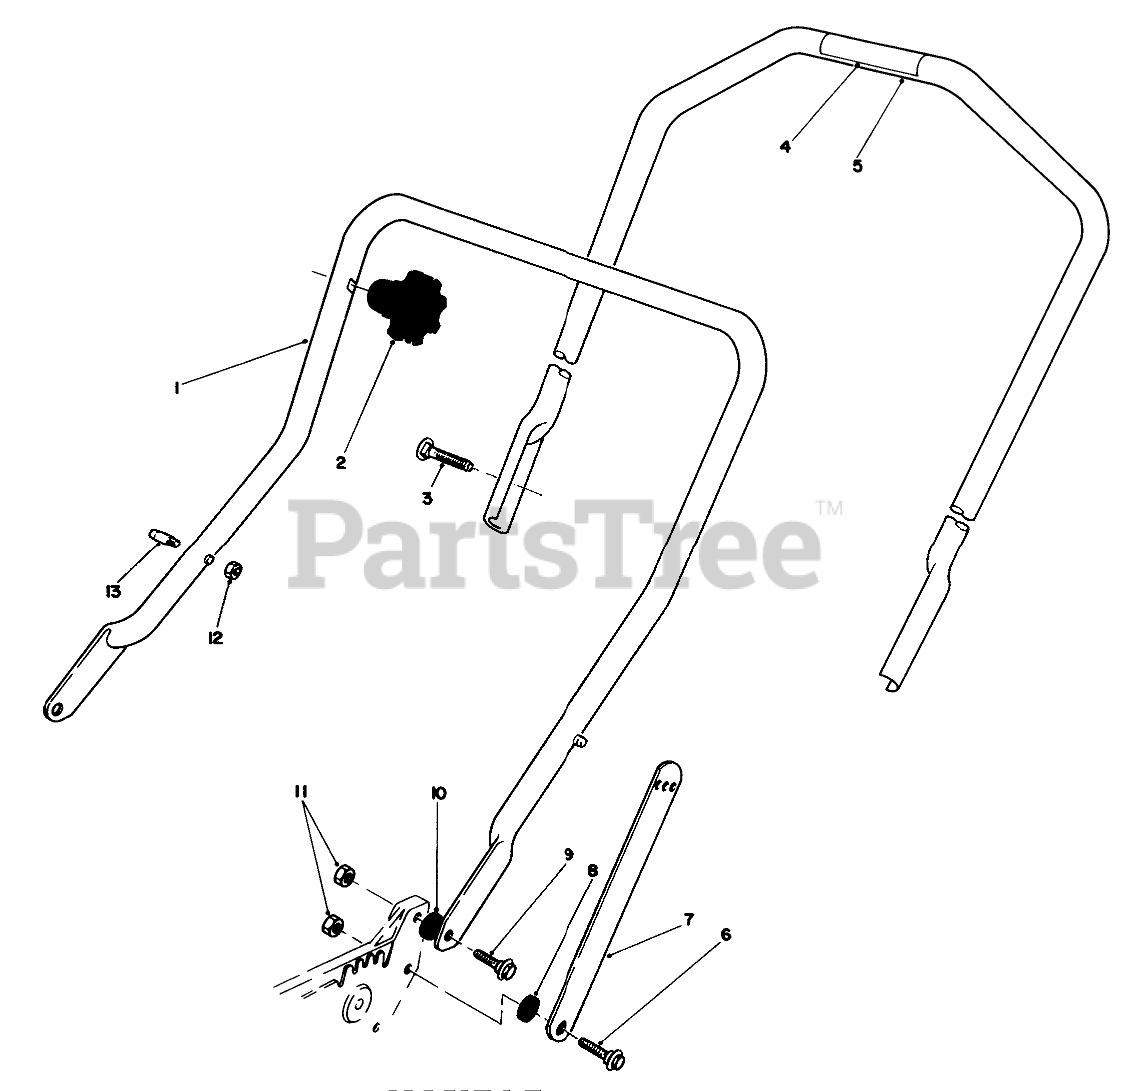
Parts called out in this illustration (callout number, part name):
1	LOWER HANDLE ASM
3	5/16-18 X 2 HNDLE SCREW
4	DANGER DECAL
5	Upper Handle Assembly (Incl. Ref. #4)
6	SCREW-SHOULDER
7	Handle Latch
8	SPACER
9	SCREW-SHOULDER
10	SPACER
11	NUT-LOCK, NI
12	NUT-LOCK, NI
13	HANDLE PIN
